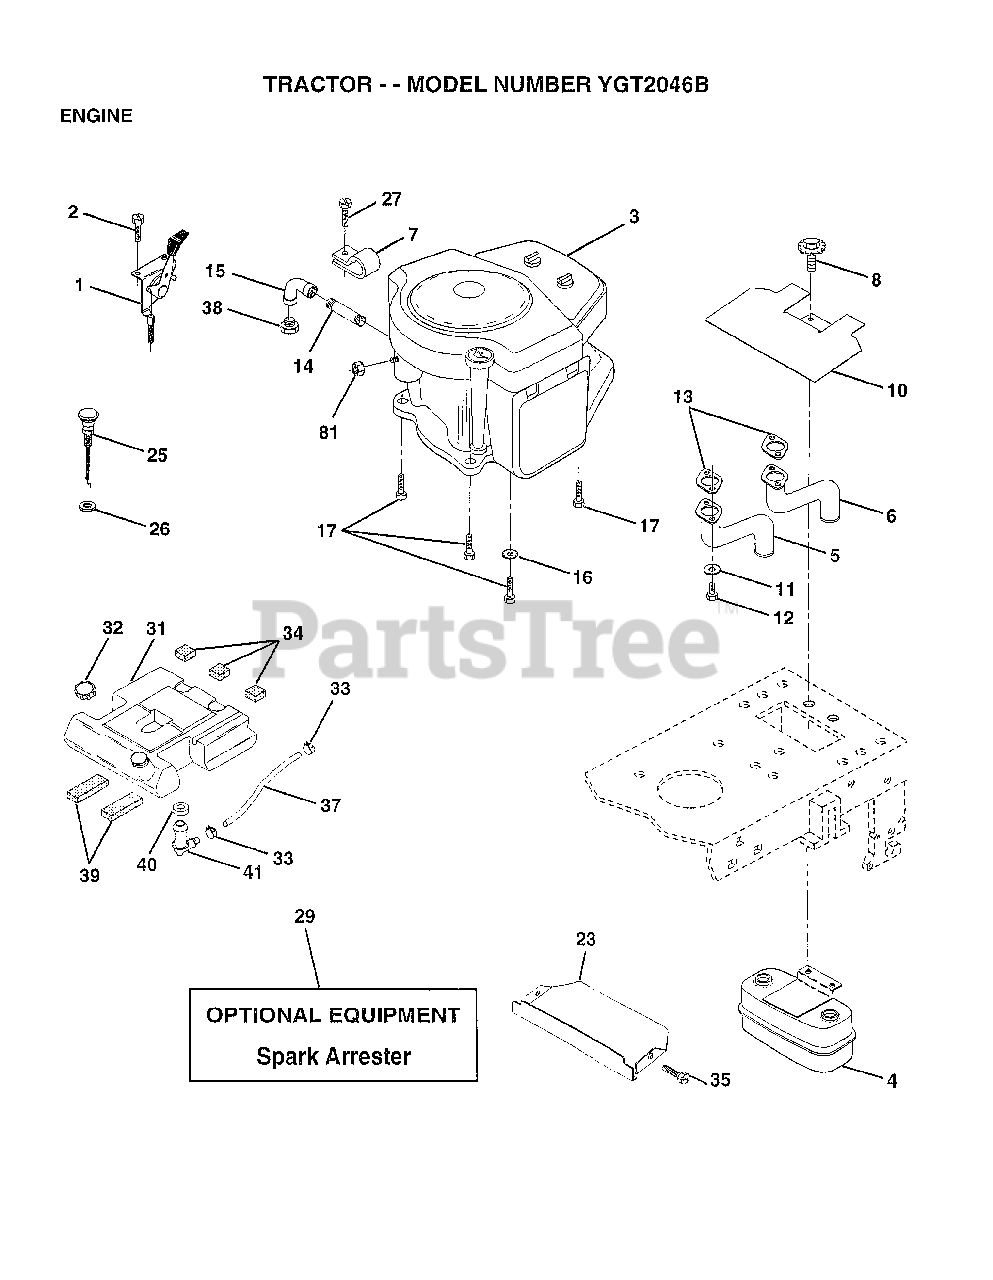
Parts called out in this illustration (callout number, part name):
2	SCREW LT
4	MUFFLER.TW.LOTONE
5	TUBE MANIFOLD LH
6	TUBE MANIFOLD RH
7	CLAMP.TUBE.DBL.EN
8	BOLT.5/16-18.UNC
10	SHIELD.HEAT.
11	LOCKWASHER
12	SCREW
13	GASKET MUFFLER
14	PIPE NIPPLE LT
15	ELBOW
16	LOCKWASHER
17	SCREW LT
23	SHIELD.BRN/DBR.GD
25	"CONTROL.CHOKE.51"""
26	"NUT,KEPS 3/8-24IM"
27	"SCREW-TT,10-32 FL"
31	TANK FUEL REAR
32	CAP ASM FUEL
33	HOSE CLAMP
34	PAD-SPACER LT
35	SCREW
37	FUEL LINE T
39	PAD IDLER TI
40	BUSHING OUTLET T
41	STEM.TANK.FUEL
81	NUT
